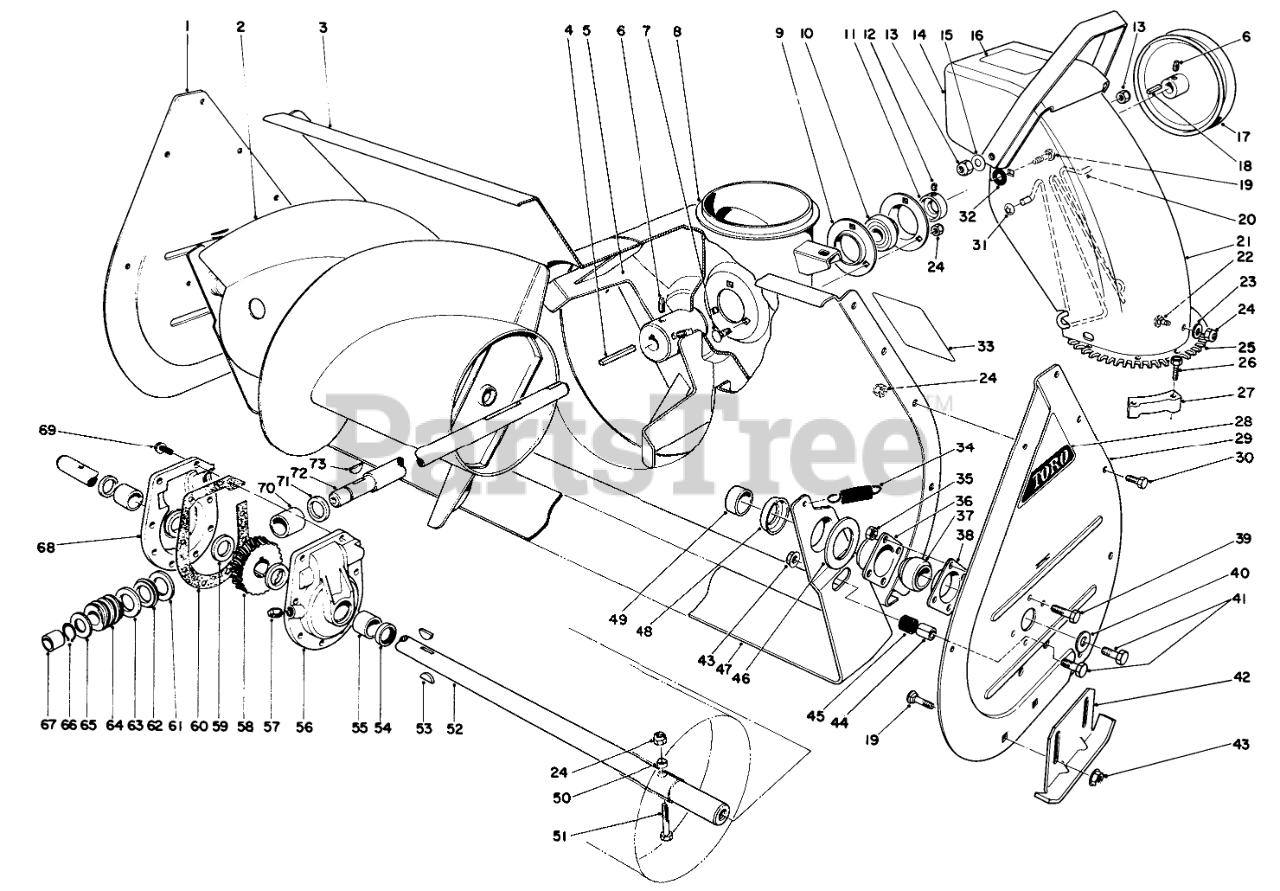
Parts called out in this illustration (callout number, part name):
1	RH AUGER SIDE PLT R
2	RH AUGER ASM - 32"
3	AUGER HSG WA 32" R
5	IMPELLER ASM
6	SCREW-SET, SQH
7	BOLT-CARR
8	CHUTE RING
9	BRG FLANGE
10	BALL BRG W/COLLAR
11	EXT LOCKING COLLAR
12	SCREW-HSH
13	NUT-LOCK, CONE
14	Deflector (Incl. Ref. #16)
15	WASHER-BELLEVILLE
16	Decal-Danger
17	1/2 X 9.5 DIA PULLEY
18	SQUARE KEY
19	SCREW-CARR
20	CHUTE WIRE
21	Upper Chute
22	SCREW-CARR
23	WASHER-PLAIN
24	NUT-LOCK, NI
25	Screw
26	SCREW-SPECIAL
27	RETAINER-CHUTE
28	AUGER SIDE PLT DECAL
29	LH AUGER SIDE PLT R
30	SCREW-HH
31	NUT-PUSH
32	WASHER-RUBBER
33	DECAL-WARNING, AUGER
34	SPRING-TENSION
35	NUT-LOCK, CONE
36	BEARING-FLANGE, FRONT
37	BEARING
38	BEARING-FLANGE, REAR
39	SCREW-HH
40	WASHER
41	SCREW-HH
42	AUGER SKID WA R
43	NUT-HF
44	SCRAPER STOP SPACER
45	SCRAPER STOP CUSHION
46	SCRAPER BLADE SPACER
47	SCRAPER BLADE 32" R
48	Positioner-Scraper
49	AUGER SPACER
50	SPACER-HUB, AUGER
51	Auger Bolt
52	32 AUGER SHAFT
53	KEY-WOODRUFF
54	SEAL-OIL
55	BUSHING
56	Gear Case L.H. (Incl. Ref. #54-55)
57	PLUG-PIPE, SQH
58	GEAR-WORM, 27T
59	WASHER-THRUST
60	GASKET-CASE, GEAR
61	WASHER-THRUST
62	BEARING-THRUST
63	THRUST-WASHER
65	WASHER-THRUST
66	Ring-Snap
67	BUSHING
68	Gear Case R.H. (Incl. Ref. #54-55)
69	SCREW-TAPTITE
70	BUSHING-SPECIAL
71	RING-QUAD
72	SHAFT-IMPELLER
73	KEY-WOODRUFF
